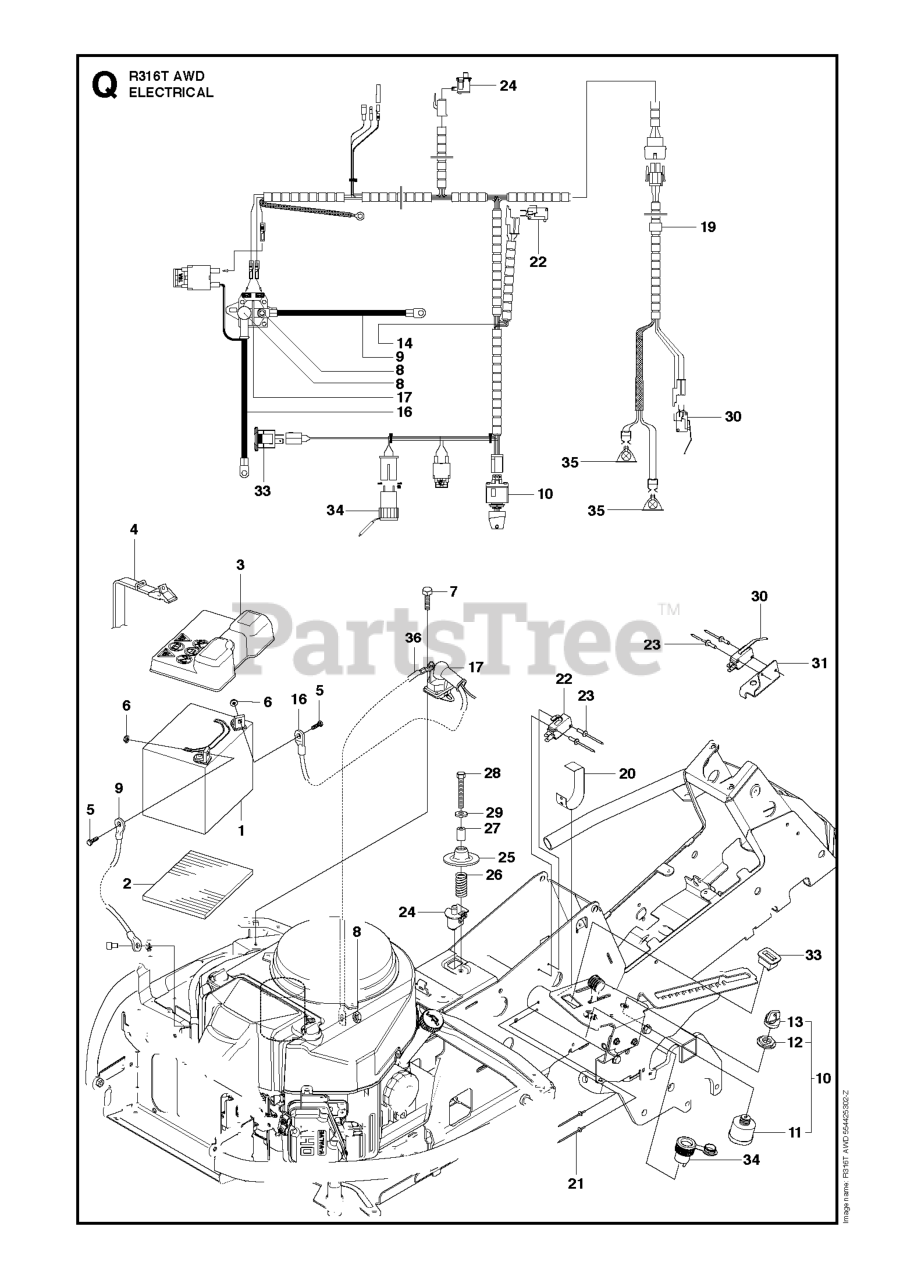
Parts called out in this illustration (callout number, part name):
8	ROD SHIFT FENDER ADJUST STLT
10	PIN COTTER
14	LOCKWASHER
15	BOLT HEX 5/16-18 GR 5
16	NUT.71038.31-18.HEX.NYLOCK
19	NUT
21	KNOB.DUCKHEAD.1/2
22	ROD BRAKE HYDRO
24	NUT
25	SPRING ROD LT
26	WASHER
27	COTTER PIN
28	ROD, PARKING BRAKE
29	PLUNGER CAP
30	BRKT, TRNSXLE MNT 20"
32	BOLT
34	SHAFT, FOOT PEDAL
35	BEARING.NYLON
37	DRIVE PIN
38	PULLEY IDLER COMPOSITE
41	KEEPER, BELT IDLER
47	IDLER PULLEY
48	BELLCRANK, CLUTCH
49	RETAIN BELT
50	BOLT.3/8-16X1.50
52	LOCKNUT
53	LINK, CLUTCH LT
55	SPRING, RETURN LT
56	SCREW.3/8-16
57	DRIVE BELT, LTH & YTH TRACTORS
59	KEEPER, BELT CENTER
61	SCREW 3/8-16X.875
62	COVER, PEDAL (1 2)
64	BOLT HEX 7/16-20X4-1/4"
65	LOCKWASHER
66	KEEPER BELT ENGINE
69	SCREW.HI-LO.CONSOLE
71	STRAP TORQUE LH HYDRO
73	STRAP TORQUE RH HYDRO
74	SPACER AXLE
77	SQUARE KEY
81	SHAFT ASM CROSS TAPERED
82	SHIFT SPRING
83	WASHER
84	LINK TRANSAXLE
89	CONSOLE SHIFT STL AUTO
95	CONTROL ASM. BYPASS HYDRO
96	RETAINER M
116	BOLT D
120	NUT LOCK FLG 3/8-16 UNC
150	SPACER, RETAINER
151	WASHER 12/32X2X10GA
156	WASHER.SRRTD.5/16
158	BRACKET
159	RB HUB.SHIFT
161	BOLT
162	NUT.CROWNLOCK.1/4
165	RP BRACKET
166	CAPSCREW.HXHD.FLG.5/16-18X.625
168	BOLT.SHOULDER.5/16-18X
169	PLATE.FASTENING.CROSS.SHAFT
197	NYLINER SNAP 5/8" ID
198	WASHER.NYL.7/8IDX.105"HYD CR
199	BOLT SHOULDER 5/16-18 UNC
212	NUT
250	SCREW 3/8-16X3/4
